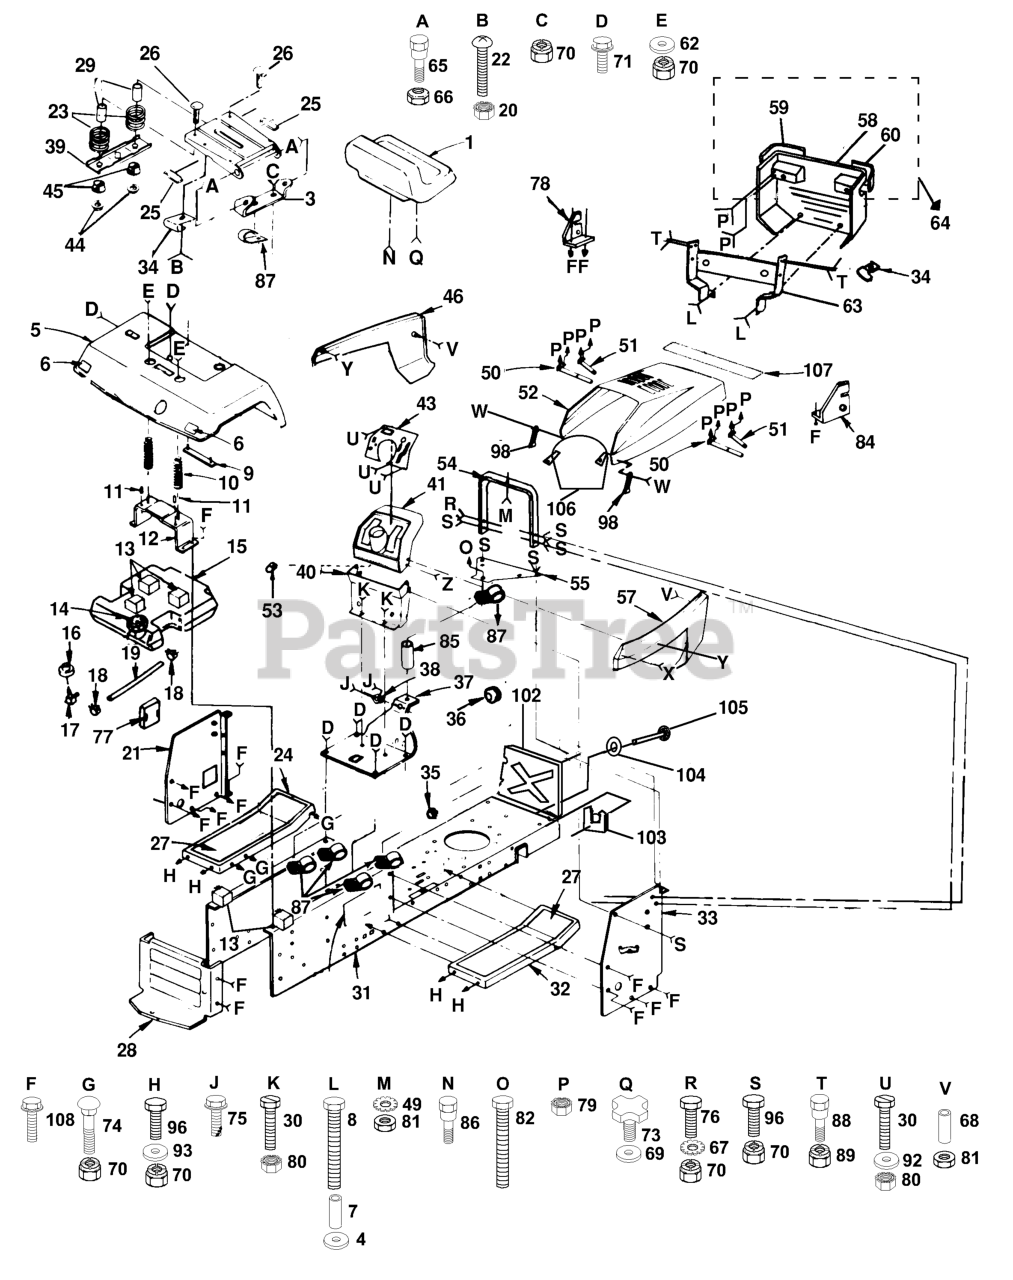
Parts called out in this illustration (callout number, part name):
1	SEAT
3	BRKT,SEAT PIVOT
4	WASHER PM
5	FENDER
6	REFLECTOR-TAIL YT
9	STRAP-FENDER YT
10	SPRING COMPRESSION
11	NUT-PUSH YT
12	BRACKET-FENDER YT
13	PAD-SPACER T
14	FUEL CAP ASS'Y
15	FUEL TANK LT
16	BUSHING OUTLET T
17	FUEL TANK STEM GT
18	HOSE CLAMP
19	FUEL LINE T
20	Nut, Keps #10
21	PANEL DASH LH NLA
23	SPRING COMPRESSED
24	ROLL PIN NLA
25	STRIP FORM
26	Bolt, Carriage 1/4-20 x 1-1/4
27	PAD FOOTREST T
28	DRAWBAR
29	SPACER SPLIT
30	Screw, Mach. Cr. Thd. 5/16-18 x 3/4
32	PAD,SPACER
33	PANEL LT NLA
34	CLIP T
35	SNAP BUSHING T
36	SNAP BUSHING T
37	SADDLE
38	BUSHING LT
39	BRKT SWITCH
40	DASH LOWER YT NLA
41	DASHBOARD
42	WELDNUT
43	STRAP ASSY T
44	NUT T
46	PANEL,SIDE LH
49	Washer, Lock, Tooth External 1/4
50	STRAP ASSY LT
51	STRAP ASSY LT
52	HOOD
53	PLUG BUTTON T
54	SUPPORT ASS'Y
55	PLATE SUPPORT T NLA
57	PANEL,SIDE RH
58	GRILL
59	LENS LH
60	LENS RH
62	WASHER
63	SUPPORT ASS'Y
64	GRILL COMPLETE
65	BOLT, SHOULDER LT
66	LOCKNUT
67	LOCKWASHER
68	SPACER NLA
71	SCREW LT
73	KNOB 1/2" YT
74	Bolt, Carriage 3/8-16 x 3/4
75	SCREW LT
76	BOLT
77	COVER ACCESS
78	SUPPORT LH YTH
79	NUT
80	NUT
81	NUT
82	Bolt, Hex 5/16-18 x 2
84	SUPPORT RH YTH
86	BOLT,SHOULD
87	CLIP T
88	BOLT T
89	NUT.CROWNLOCK.1/4
92	WASHER
93	WASHER
98	LATCH.HOOD.
102	SHIELD HEAT HYT
103	RECEPTACLE LT
104	RETAINER LT
105	STUD 1/4 TURN
106	BAFFLE,REAR UPPER
107	FOAM-STRIP LT
108	SCREW
